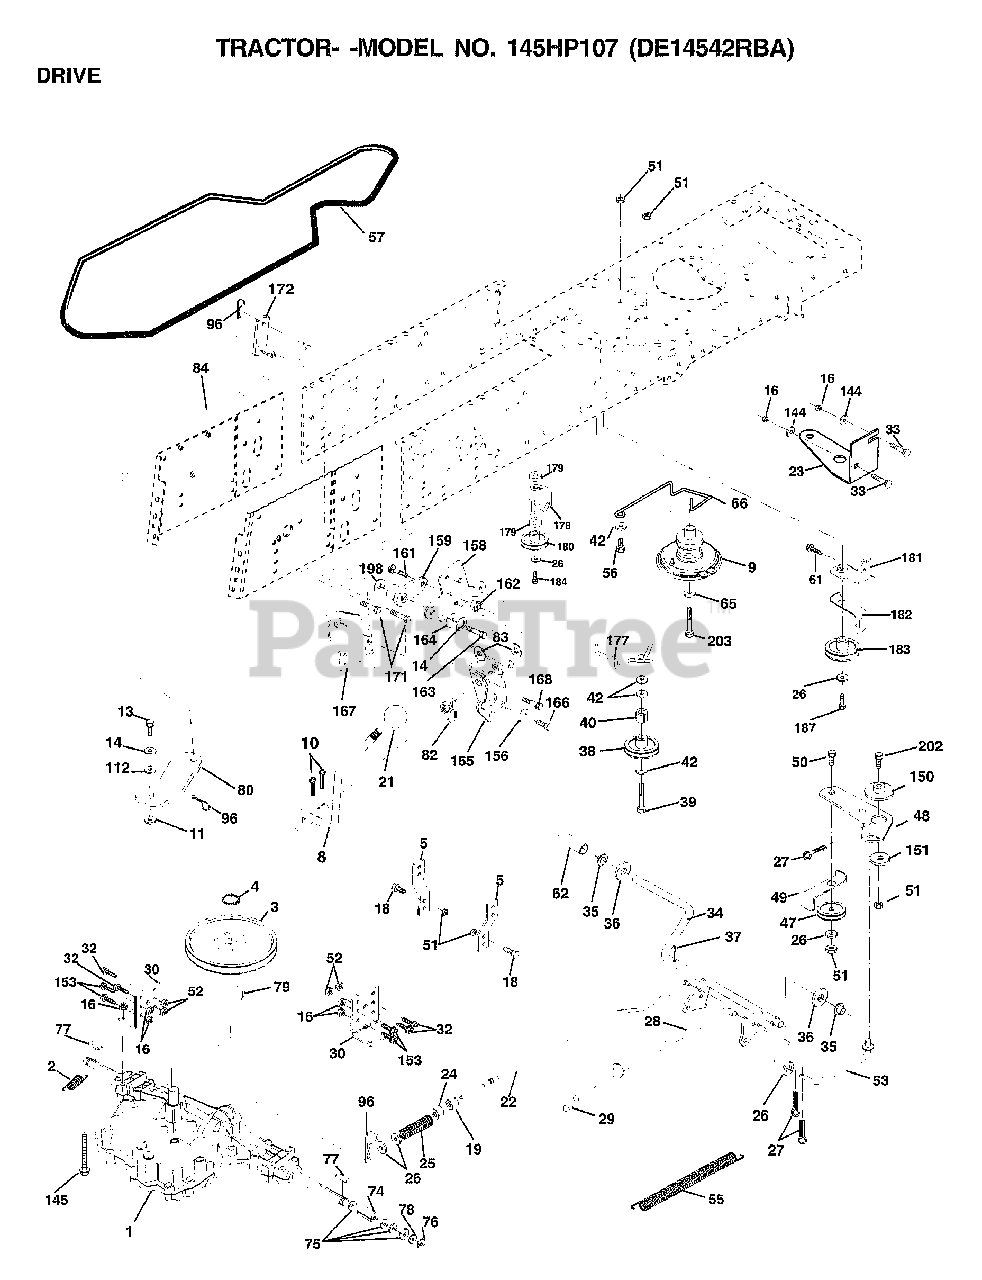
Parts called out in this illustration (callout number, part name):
2	SPRING.BRAKE.RETU
3	"PULLEY.TRANSAXLE.7"""
5	STRAP TORQUE
8	ROD.SHIFT.FENDER.ADJ.LT.CRD
9	CLUTCH ASM NORAM
10	PIN COTTER 1/8
11	WASH-SHFT PLT LT
13	BOLT.1/4-28.W/PAT
14	LOCKWASHER
16	NUT
18	BOLT
19	NUT
21	KNOB T (1/2-HOLE)
22	ROD.BRAKE.PMST.CRD
23	BRACKET CLUTCH
24	NUT
25	SPRING ROD LT
26	WASHER
27	COTTER PIN
28	ROD.BRAKE.PARK.LT
29	PLUNGER CAP T
30	TRANSAXLE MTG BKT
32	BOLT
33	BOLT
34	SHAFT.ASM.PEDAL.FOOT.CRD
35	NYLON BEARING
36	WASHER LT
38	PULLEY.FLAT
39	BOLT
40	SPACER T
42	WASHER
48	BELLCRANK.CLUTCH
49	RETAIN BELT
53	"LINK, CLUTCH T"
55	"SPRING, RETURN LT"
57	"V-BELT.KEV.111"""
61	SCREW
62	PEDAL COVER T
65	LOCKWASHER
66	KEEPER-BELT
74	SPACER AXLE
75	WASHER
76	E-RING LT
77	SQUARE KEY
78	WASHER
80	"ARM.SHIFT.20""TIRE"
82	"SPRING,TORSION"
83	WASHER
84	LINK.SHIFT.CRD
96	RETAINER M
112	WASHER LT
144	WASHER
145	BOLT.HEX.FLGHD
150	BUSHING.BELLCRANK.GRD.DR
151	WASHER
156	WASHER.SRRTD.5/16
158	BRKT.SHIFT.MOUNT
159	HUB.SHIFT
161	BOLT T
164	WASHER.5/8X.281X10GA
165	BRKT.PIVOT.LEVER
166	SCREW.5/16-18X5/8
167	BRKT.SUPT.SHIFT.CRD
168	BOLT.SHOULDER.5/16-18X.561
171	SCREW LT
172	SHAFT.ASM.SHIFT.FRT.CRD
177	KEEPOER.FLAT.IDLER
178	KEEPER.BELT.IDLER
179	WASHER
180	PULLEY.FLAT.IDLER
181	BRKT.IDLER.GRD.DR.CRD
182	"KEEPER.BELT.2.5"".OD.CRD"
183	PULLEY.V-IDLER
184	SCREW.HXWSH.3/8
187	SCREW
198	WASHER NYLINER
202	BOLT.3/8-16X1.50
203	BOLT HEX
